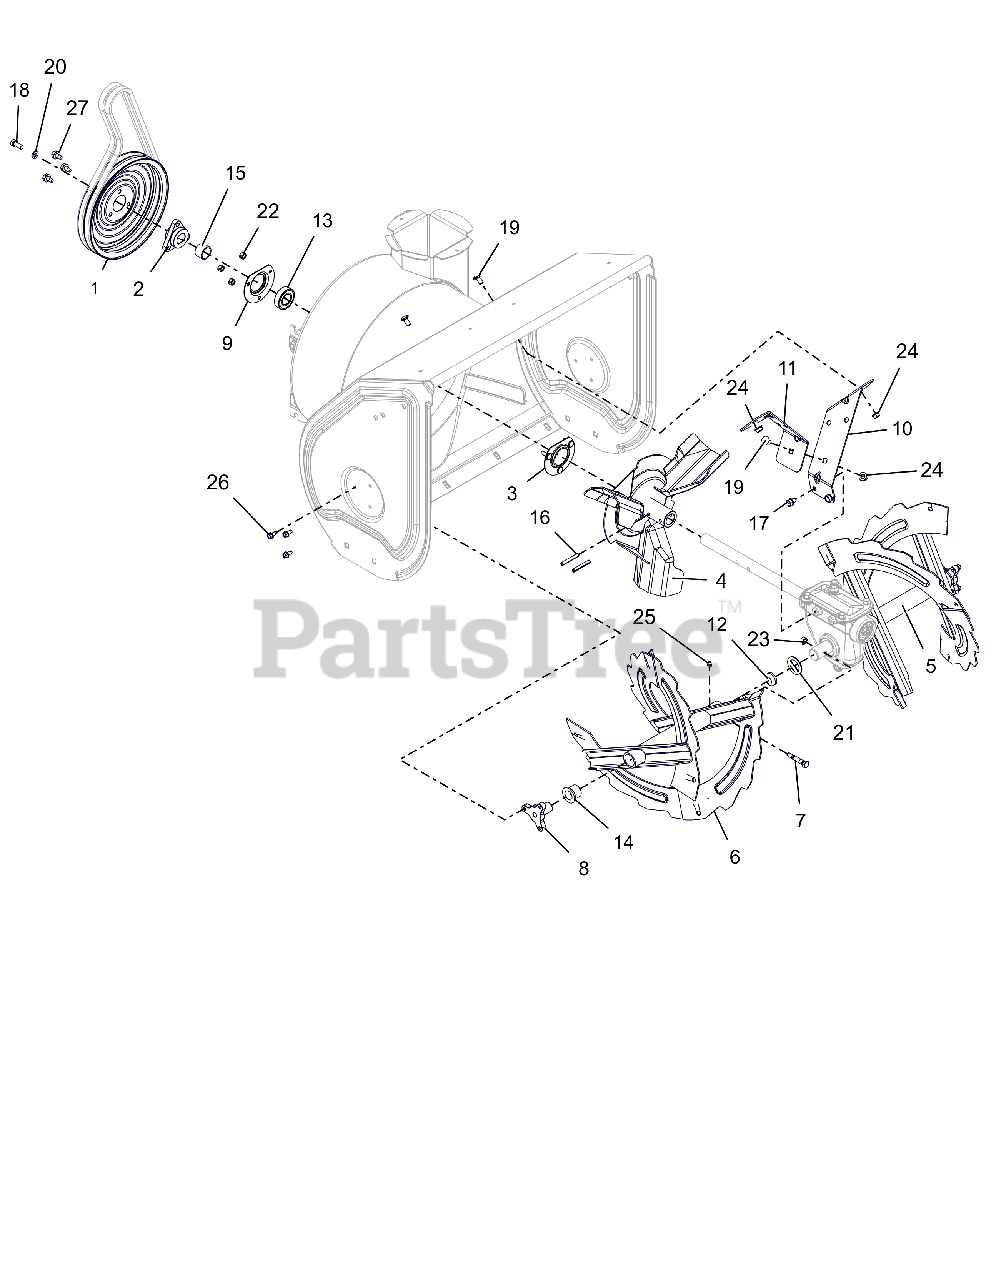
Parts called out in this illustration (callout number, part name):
1	PULLEY, SPIN FORM DUAL GROOVE
2	PULLEY HUB, D-BORE .87 DELUXE
3	BEARING FLANGE
4	IMPELLER, 3 BLADE-14"
5	RAKE, LH W/ZERK - 24"
6	RAKE, RH W/ZERK - 24"
7	BOLT, SHEAR - DELUXE
8	SUPPORT, RAKE BUSHING
9	BEARING FLANGE
10	BRACKET, GEARCASE SUPPORT - LH
11	BRACKET, GEARCASE SUPPORT - RH
12	PLUG, RAKE TUBE
13	BRG-BALL .876 X 1.750 X .50
14	BSHG-FLG, NY.778 ID X 1.018 OD
15	BSHG,SPCR .895X1.065X.693
16	PIN-ROLL .250X1.75
17	BOLT, SEMS .31-18X.50 GR5 YWZC
18	BLT-HEX .31-24X.75 YWZC GR5
19	BLT-RDHDSQSHNK.31-18X.62 YZ-LK
20	WSHR-LK .312X.097 HVY YWZC
21	WSHR-FL-STL 1.010X1.505X.062YZ
22	@NUT-LK-CTR .25-20 YWZC
23	@NUT-LK-CTR .31-18 YWZC
24	@NUT-LK-TOP-FLG .31-18 YWZC
25	ZERK,FITTING .25X.125 DRIVE IN
26	SCR-TAP .25-20X.50 HWH TR YWZ
27	@SCR-TAP .31-18X.50 HWH TR YWZ
